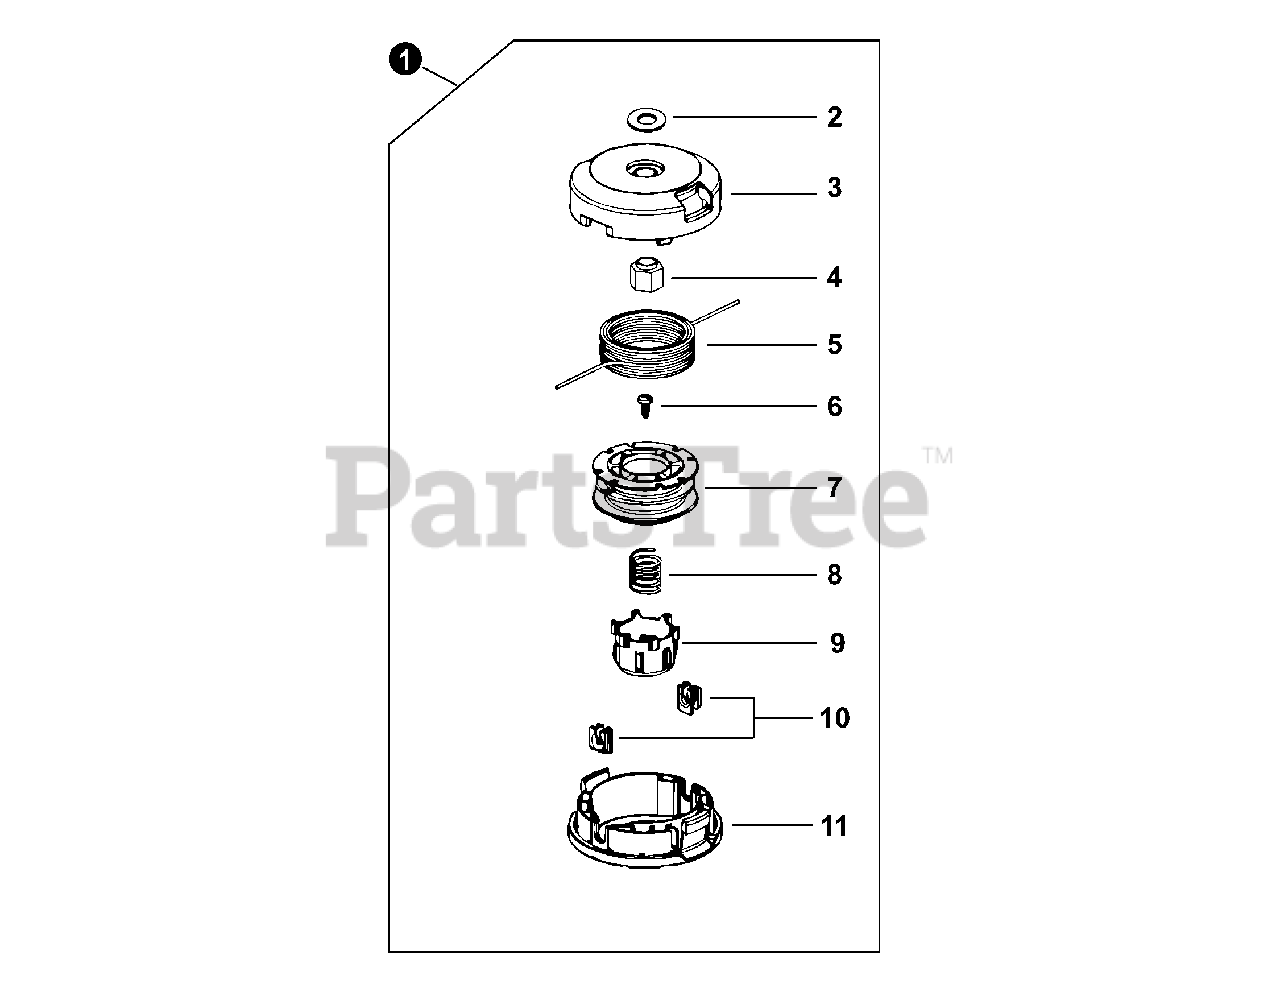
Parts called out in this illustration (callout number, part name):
1	TRIMMER HEAD
2	WASHER 24
3	COVER, SPOOL
4	BUSHING
5	LINE, NYLON TRIMMER
11	HOUSING, SPOOL
